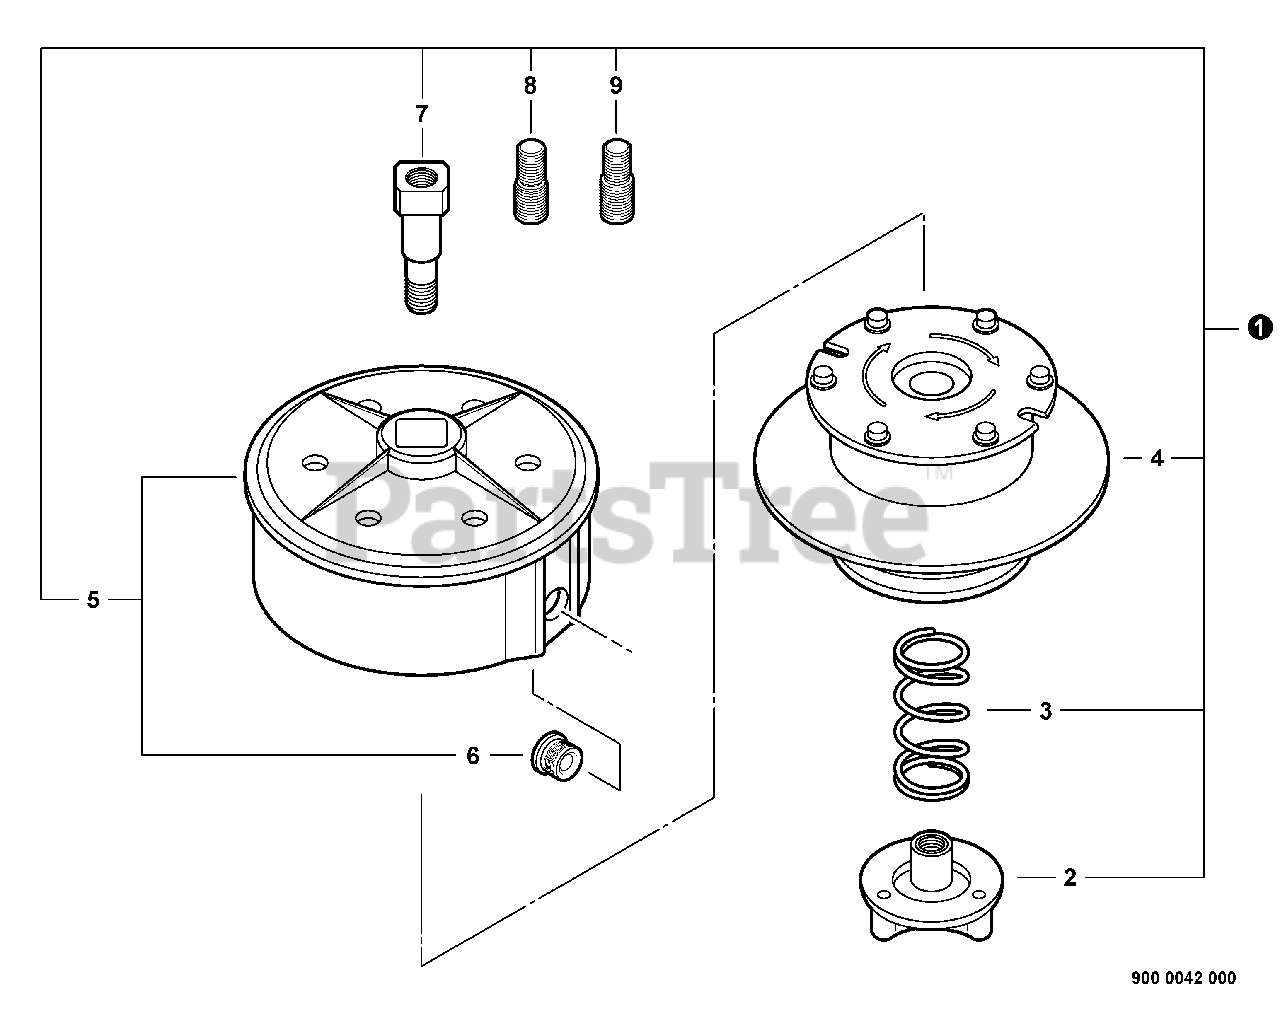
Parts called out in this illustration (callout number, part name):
1	HIGH CAPACITY MANUAL TRIMMER HEAD
2	WINGNUT
5	SPOOL COVER ASSY
7	ARBOR - LEFT HAND
8	STUD - GOLD -- LEFT HAND
9	STUD - SILVER -- LEFT HAND
